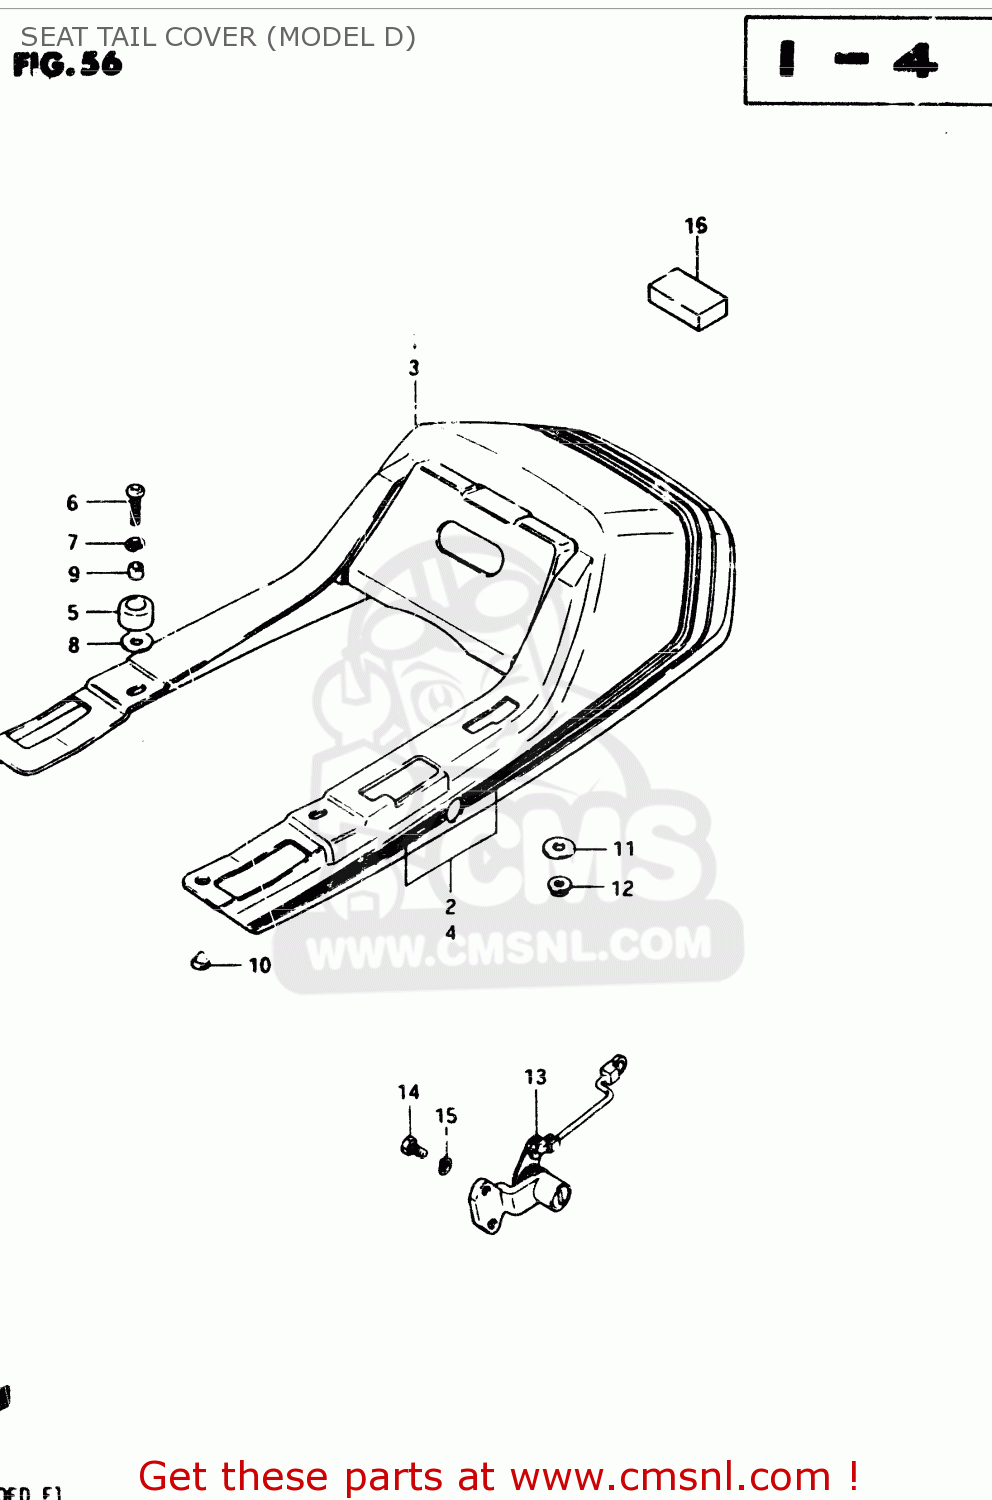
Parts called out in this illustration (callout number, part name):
1	COVER,SEAT TAI
2	TAPE SET SEAT TAIL COVER
3	COVER,SEAT TAI
4	TAPE SET, SEAT TAIL COVER
5	CUSHION,COVER
6	SCREW
7	LOCK WASHER
8	WASHER (6.5X24X1.6)
9	SPACER
10	CUSHION
11	WASHER
12	NUT 6MM
13	LOCK ASSEMBLY,SEAT
14	BOLT 5X10
15	LOCK WASHER
16	CUSHION
